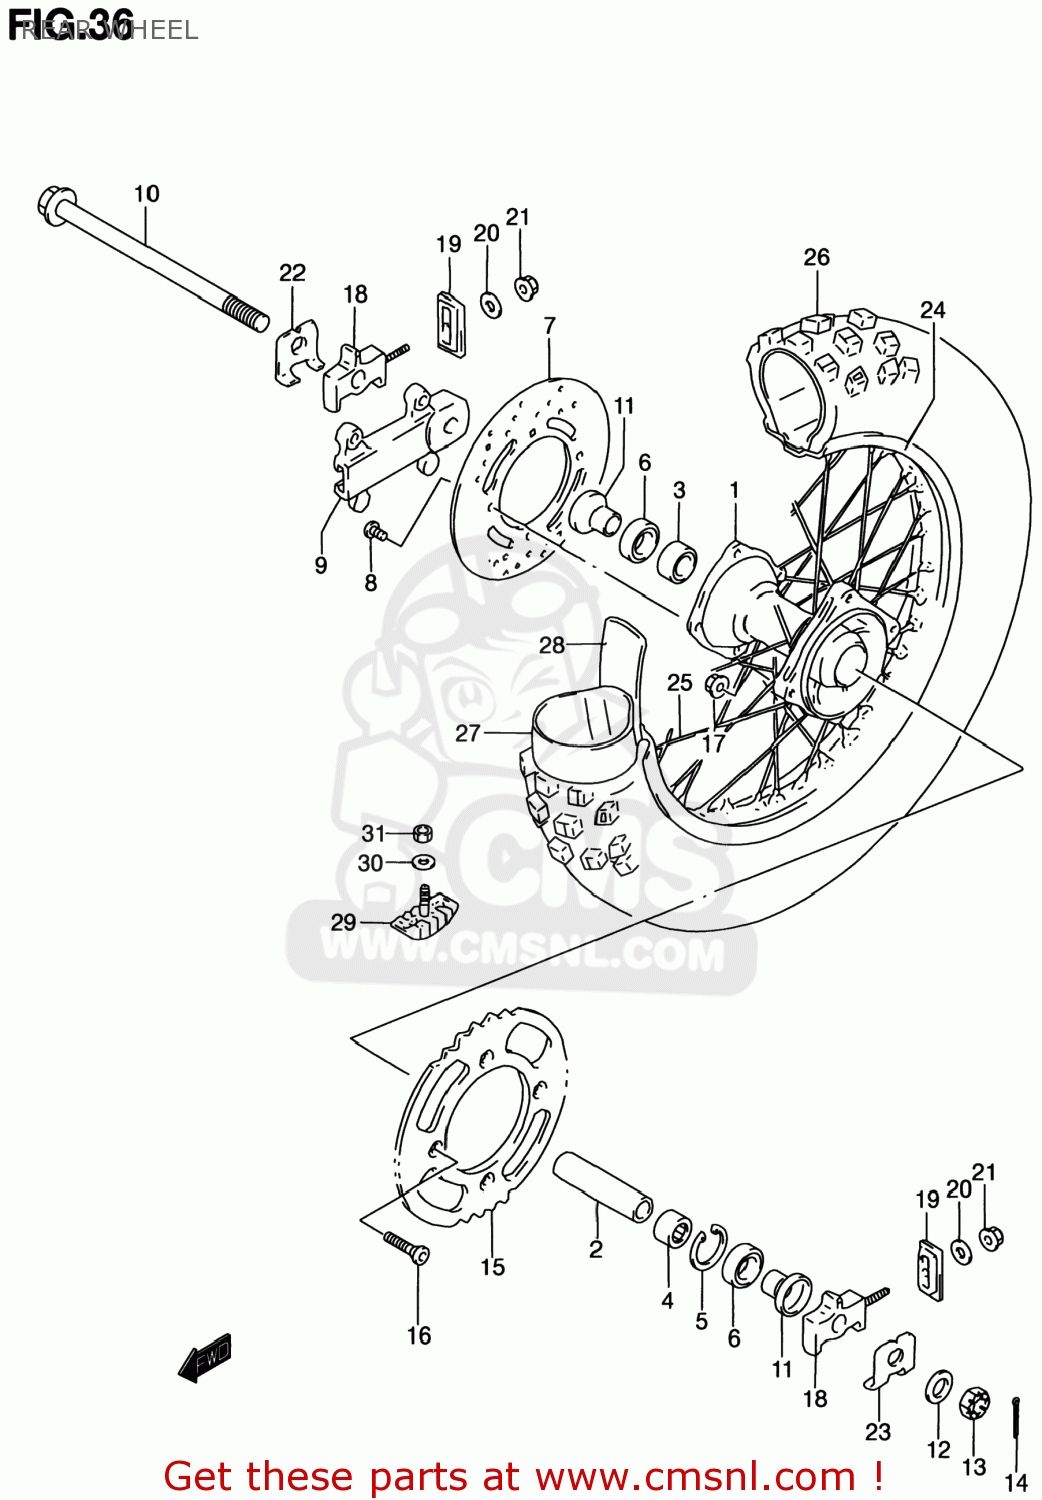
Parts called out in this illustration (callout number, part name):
1	HUB,RR WHEEL
2	SPACER,RR HUB BEARING
3	BEARING
4	BEARING(15X35X11)
5	CIRCLIP
6	SEAL,OIL(20X35X7)
7	DISC,REAR BRAKE
8	SCREW
9	BRACKET,RR AXLE
10	AXLE,RR
11	SPACER,RR AXLE
12	WASHER
13	NUT
14	COTTER PIN
15	SPROCKET,RR(49T)
16	BOLT(8X30.5)
17	NUT
18	ADJUSTER,CHAIN
19	PLATE,CHAIN ADJUSTER
20	WASHER
21	NUT 6MM
22	WASHER,CHAIN ADJUSTER RH
23	WASHER,CHAIN ADJUSTER,L
24	RIM,RR WHEEL(1.60X14 AL)
25	SPOKE ASSY,RR WHEEL
26	TIRE,REAR 90/100-14 D7
27	TUBE ASSY,WHEEL INNER
28	PROTECTOR,WHEEL,INNER
29	STOPPER,BEAD(1.85)
30	WASHER
31	NUT
